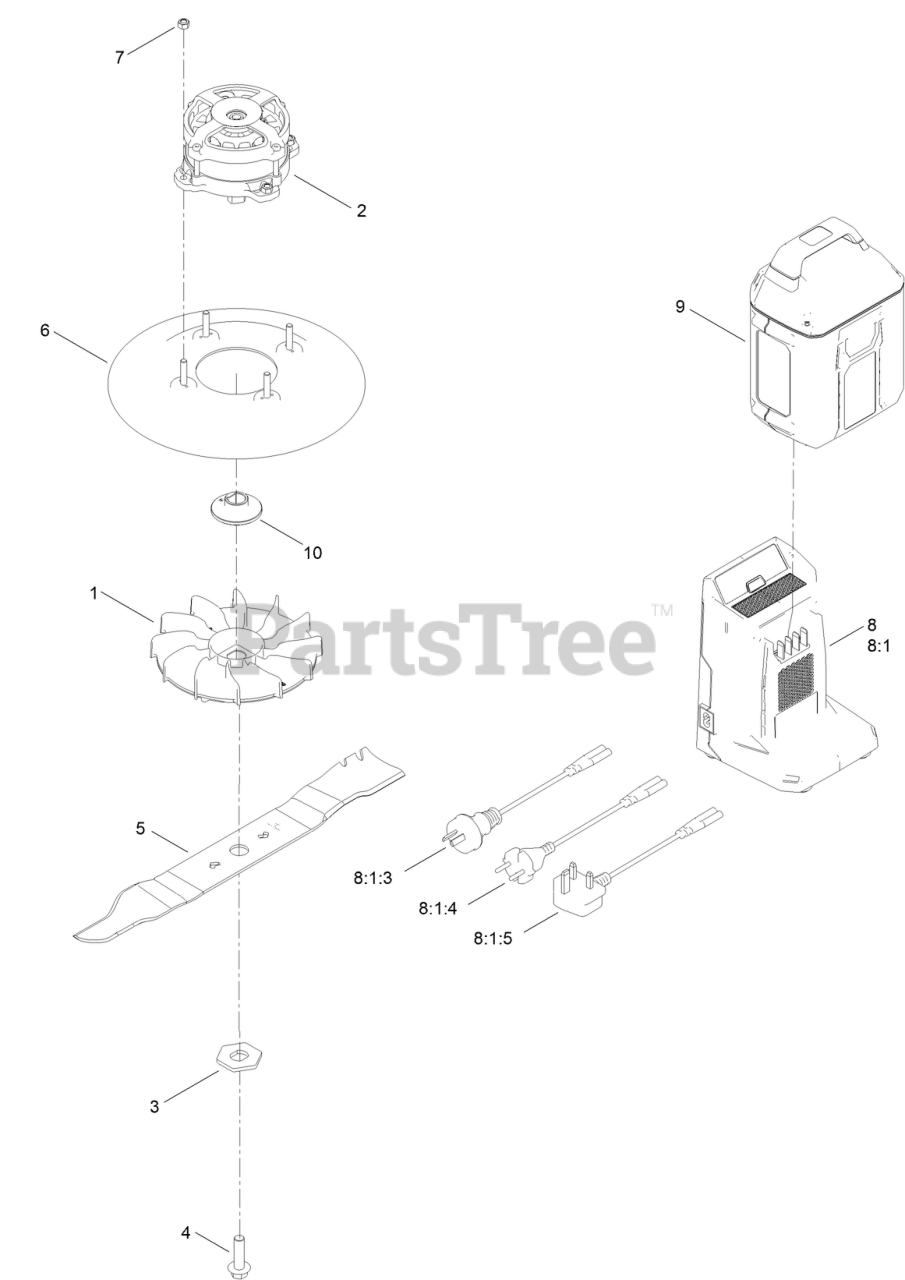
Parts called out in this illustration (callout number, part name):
1	FAN, SQUARE HOLE
2	MOTOR, BRUSHLESS, 60V, 850W
3	WASHER, HEX
4	BLADE BOLT
5	BLADE, MULCH, 43CM
5	BLADE, 43CM
6	BLADE COVER
7	NUT, NYLOC, M6X1
8	60V CHARGER CE
8	60V BATTERY CHARGER 2 AMP CE HAYTER
8:1	60V CHARGER 2 AMP
8:1:3	CORD-CHARGER, AU/NZ
8:1:4	CORD-CHARGER, CE
8:1:5	CORD-CHARGER, UK
9	60V 4.0 AH BATTERY CE
9	BATTERY-LI-ION, 60V 4.0AH, CE, HYTR
10	BOSS, BLADE SINTERED
